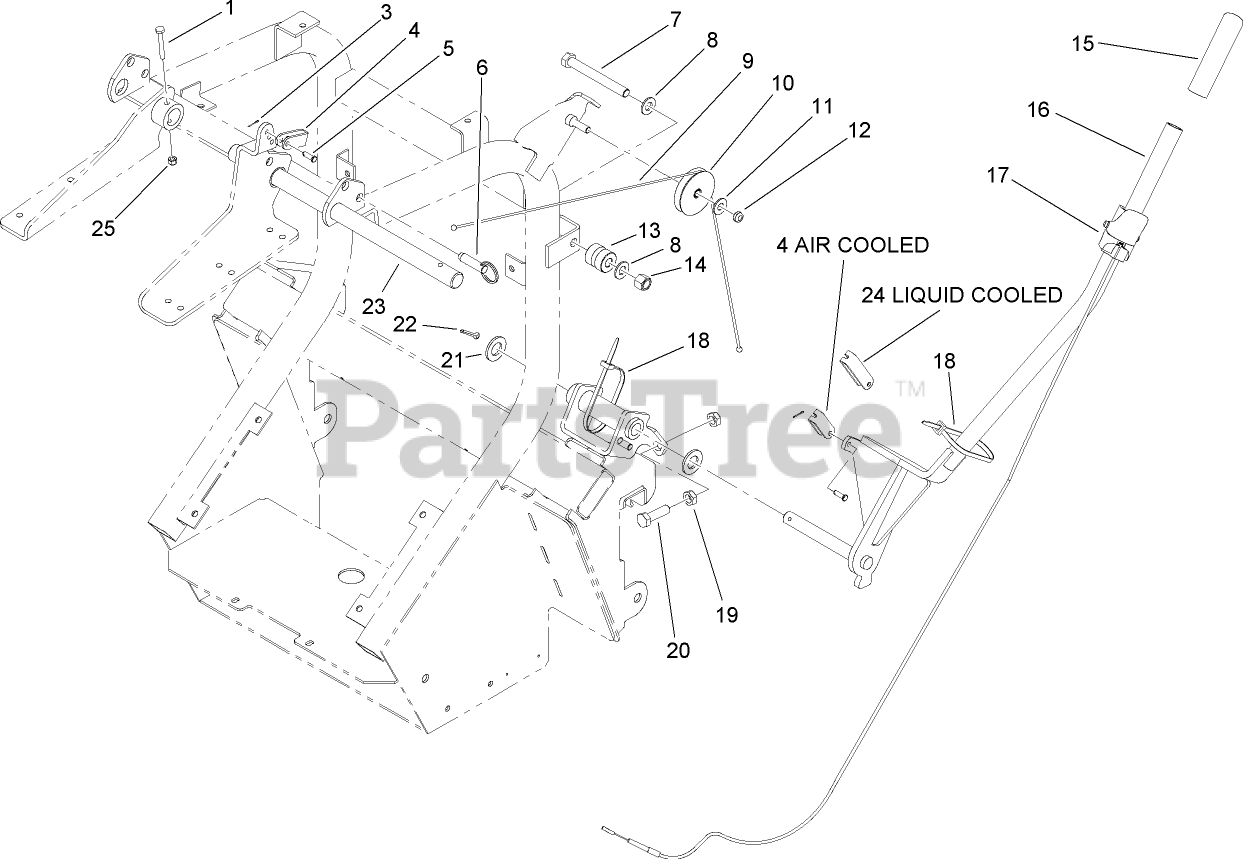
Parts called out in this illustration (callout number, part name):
1	SCREW-HH
3	PIN-COTTER
4	CLEVIS-SHORT
5	PIN-CLEVIS
6	PIN-RELEASE, QUICK
7	SCREW-HH
8	WASHER-FLAT
9	CABLE-DOOR
10	PULLEY ASM
11	WASHER-FLAT
12	NUT-LOCK, NI
13	ROLLER-CABLE
14	NUT-LOCK, NI
15	GRIP-FOAM
16	DUMP ARM ASM
17	LATCH-CABLE, DUMP
18	TIE-CABLE
19	NUT-JAM
20	SCREW-HH
21	WASHER-FLAT
22	PIN-COTTER
23	SHAFT-HINGE
24	CLEVIS-LONG
25	NUT-LOCK, NI
